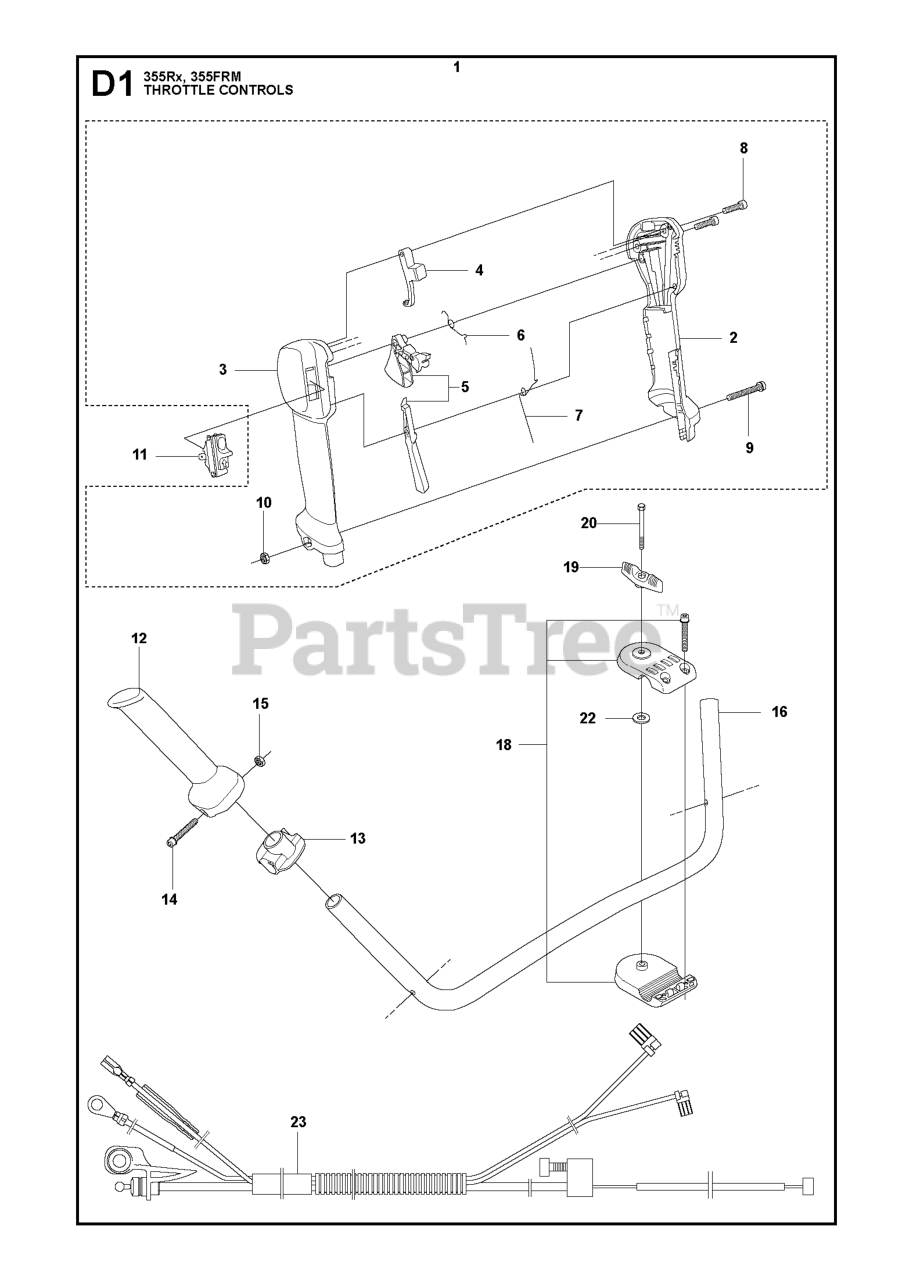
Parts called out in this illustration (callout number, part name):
1	THROTTLE HANDLE ASSY
2	HANDLE HALF RIGHT
3	HANDLE HALF LEFT
4	LOCKOUT STARTER THROTTLE
5	THROTTLE CONTROL
9	SCREW
11	STOP BUTTON
15	NUT M6M M5
16	HANDLE
18	HANDLEBAR BRACKET KIT
20	SCREW 6X70
23	WIRING ASSY SKOG
23	WIRING
